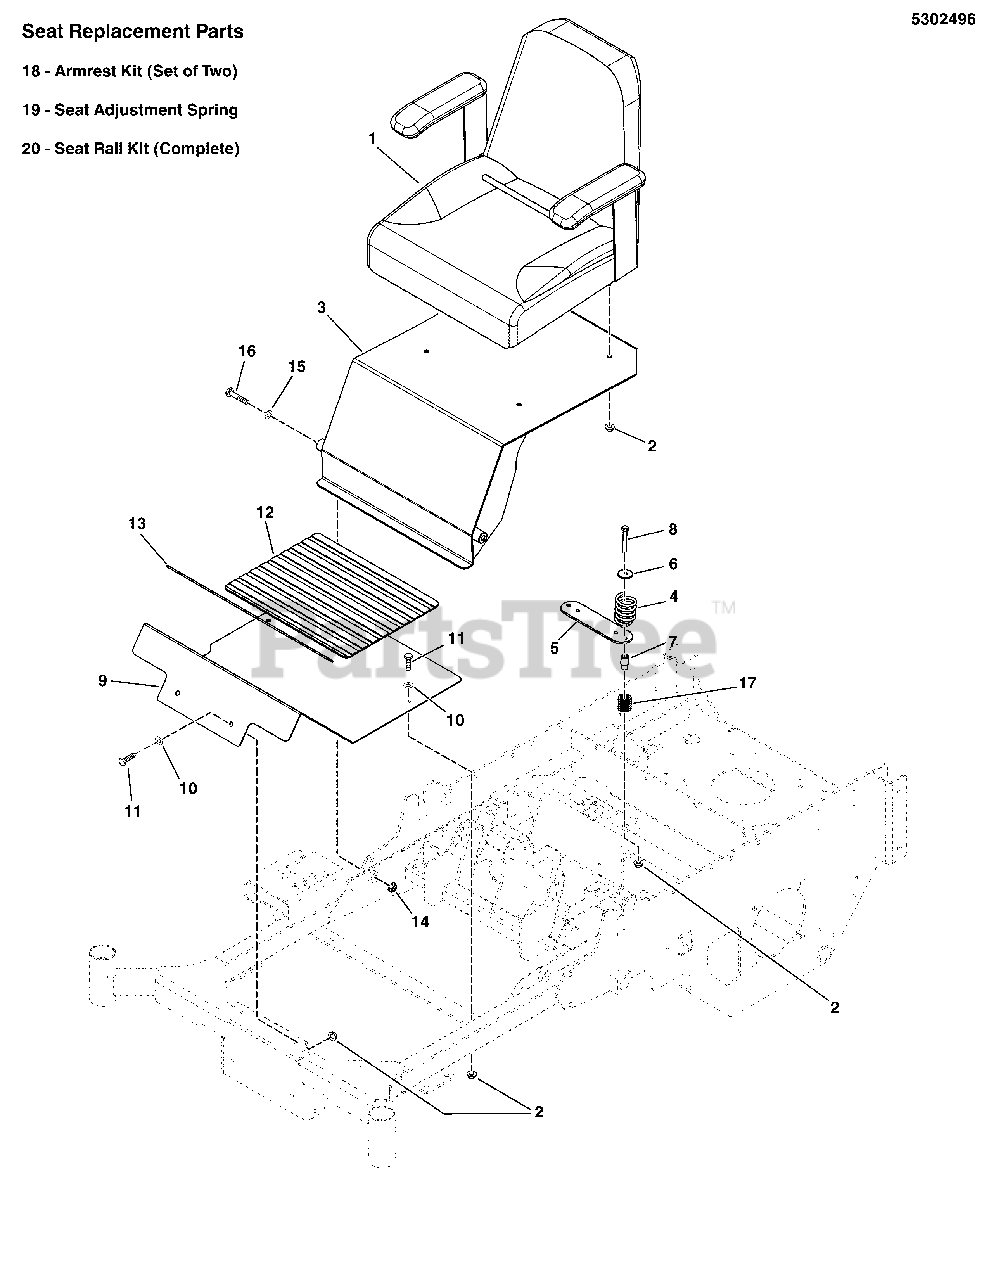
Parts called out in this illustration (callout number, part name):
1	SEAT, XB-180, NO LOGO, BLACK
2	NUT, 5/16-18 HEX NYLOCK FLANGE NUT
3	ASSM, SEAT PLATE W/ DECALS, S150XT OLD
4	SPRING, SEAT SUPPORT
5	PLATE, SEAT SWITCH - RED
6	WASHER, .34 X 1.25 X 10 GA
7	SPACER, .33 X .66 X 1.31 SHLDR, CZ
8	BOLT, 5/16-18 X 1" GRD5 YZ
9	PLATE, FLOOR PAN - RED
10	WASHER, 5/16" SAE
11	BOLT, 5/16-18 X 1" GRD5 YZ
12	SAFETY WALK, 11.50 X 15.00
13	SAFETY WALK, 8.00 X 15.00
14	NUT, 3/8 - 16 HEX NYLOCK FLANGE
15	WASHER, 3/8 SAE
16	BOLT, 3/8-16 X 2-3/4" GD5 CZ
17	SPRING COMP .76IDX1.3LGX.105WIRE BLACK
18	ARM REST KIT (SET OF TWO) (SV)
19	SPRING, EXTENSION, SEAT ADJUSTMENT (BLK OR SLVR)
20	KIT, SEAT RAILS (COMPLETE)(SV)
